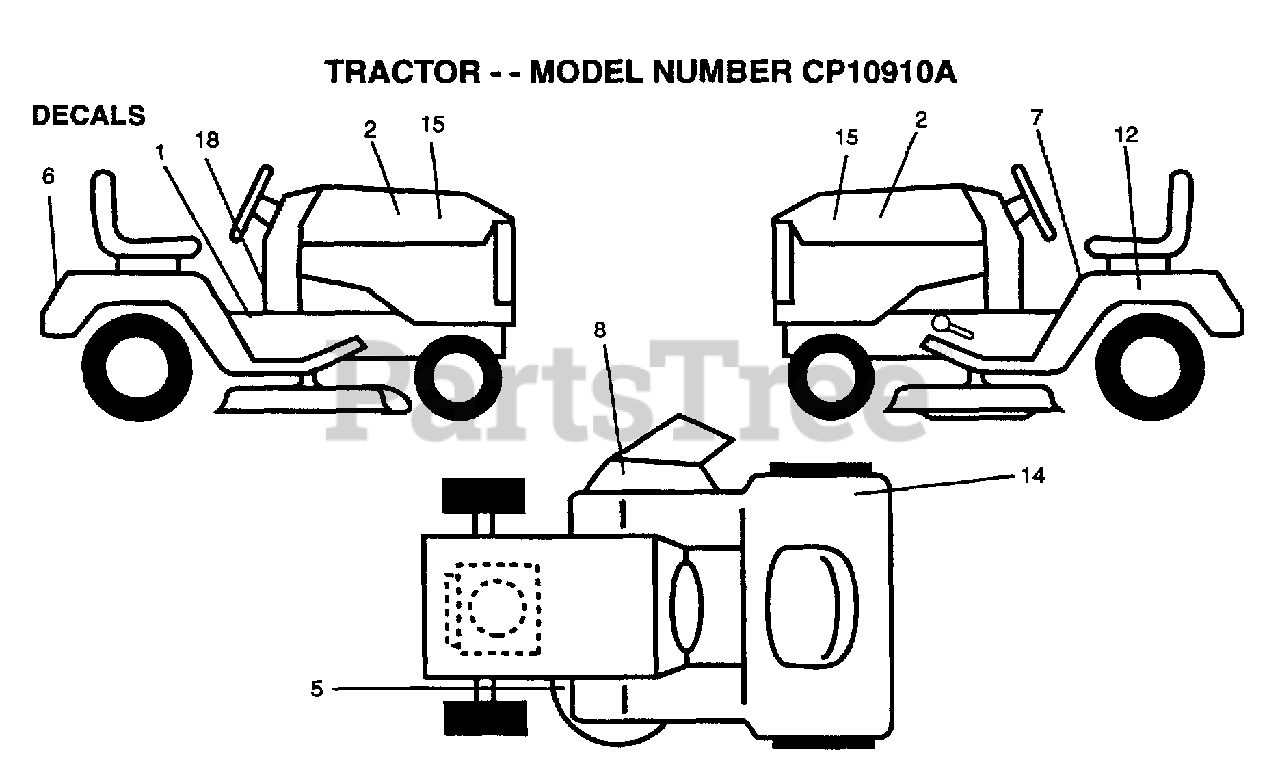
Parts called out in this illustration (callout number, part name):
1	DECAL.OP.INST.SYM
2	DECAL.HD.RH/LH.CP
5	DECAL.V.BELT
6	DECAL.FENDER.CP
7	DECAL.READ.O.MANU
8	DECAL.DANGER.CUTF
12	DECAL.BATRY.3-3908
15	DECAL.PNL.SD.CP
18	DECAL.EURO.ST.CE.
